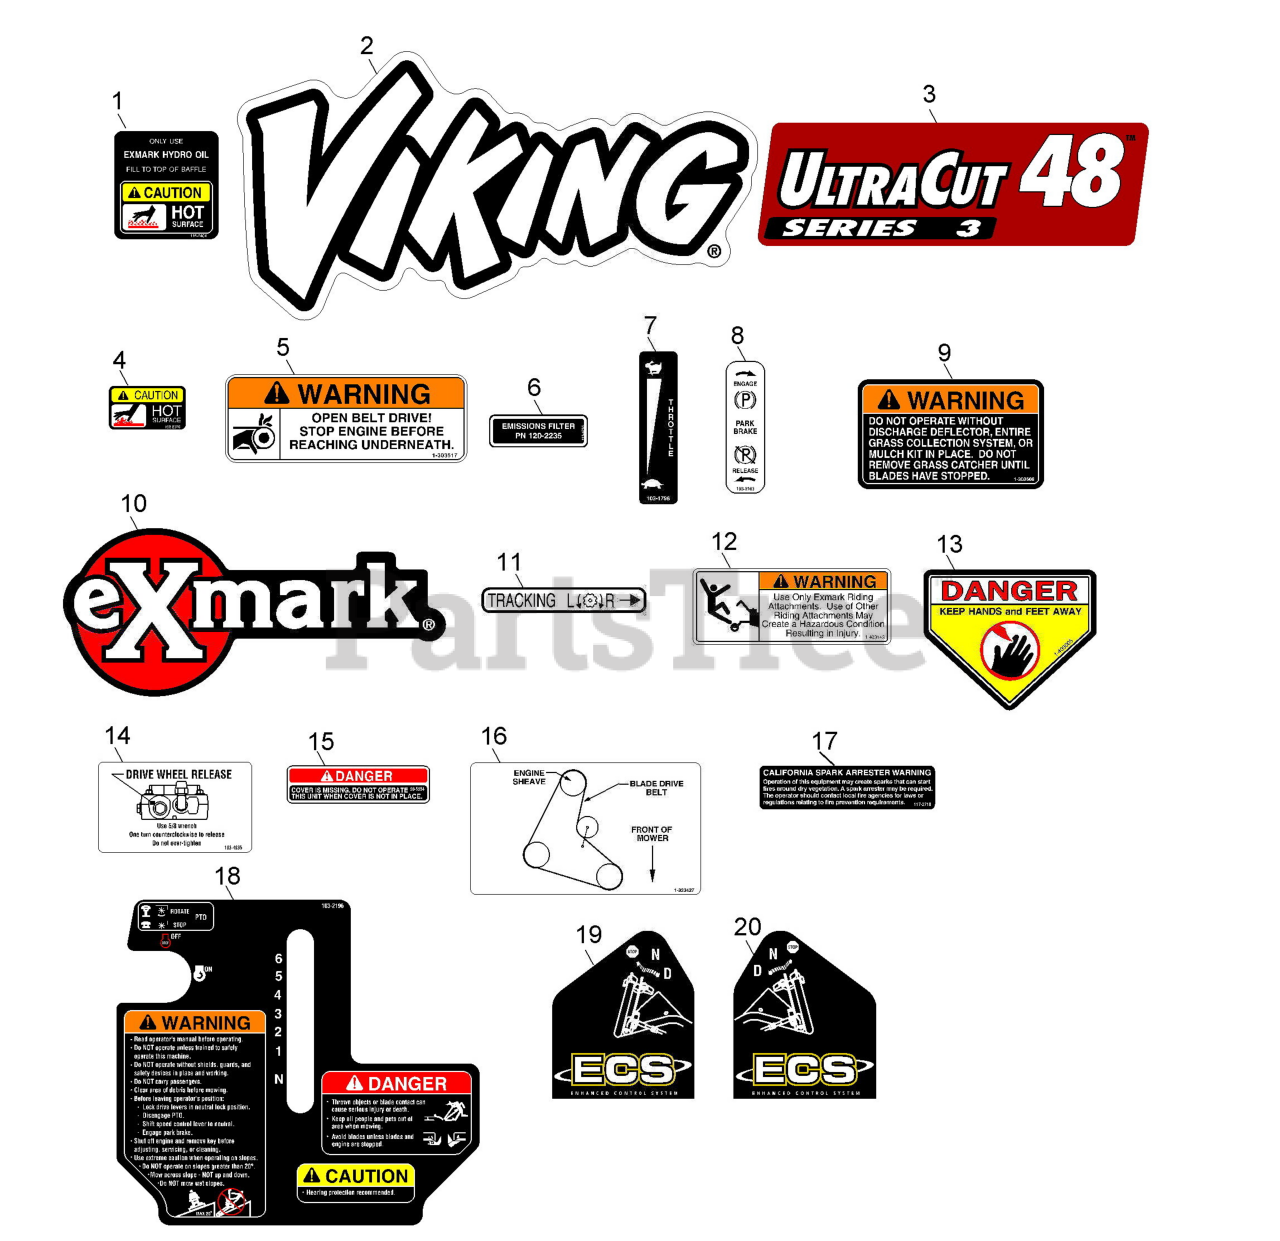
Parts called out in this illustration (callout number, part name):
1	DECAL-HYDRAULIC TANK
2	DECAL,VH MODEL
3	DECAL-ULTRACUT 48 SERIES
4	DECAL-CAUTION
5	DECAL,BELT DRIVE
6	DECAL-FILTER, EMISSIONS
7	DECAL,THROTTLE ONLY
8	DECAL-BRAKE, PARK
9	DECAL-WARNING, DISCHARGE
10	DECAL,EXMARK LOGO
11	DECAL,TRACKING ADJUST
12	DECAL,SULKY WARNING
13	DECAL-DANGER
14	DECAL,DRIVE RELEASE
15	DECAL-COVER, MISSING
16	DECAL,BELT ROUTING 32/36
17	DECAL-ARRESTER, SPARK
18	DECAL,CONSOLE VH ECS
19	DECAL,LH ECS INSTRUCTION
20	DECAL,RH ECS INSTRUCTION
